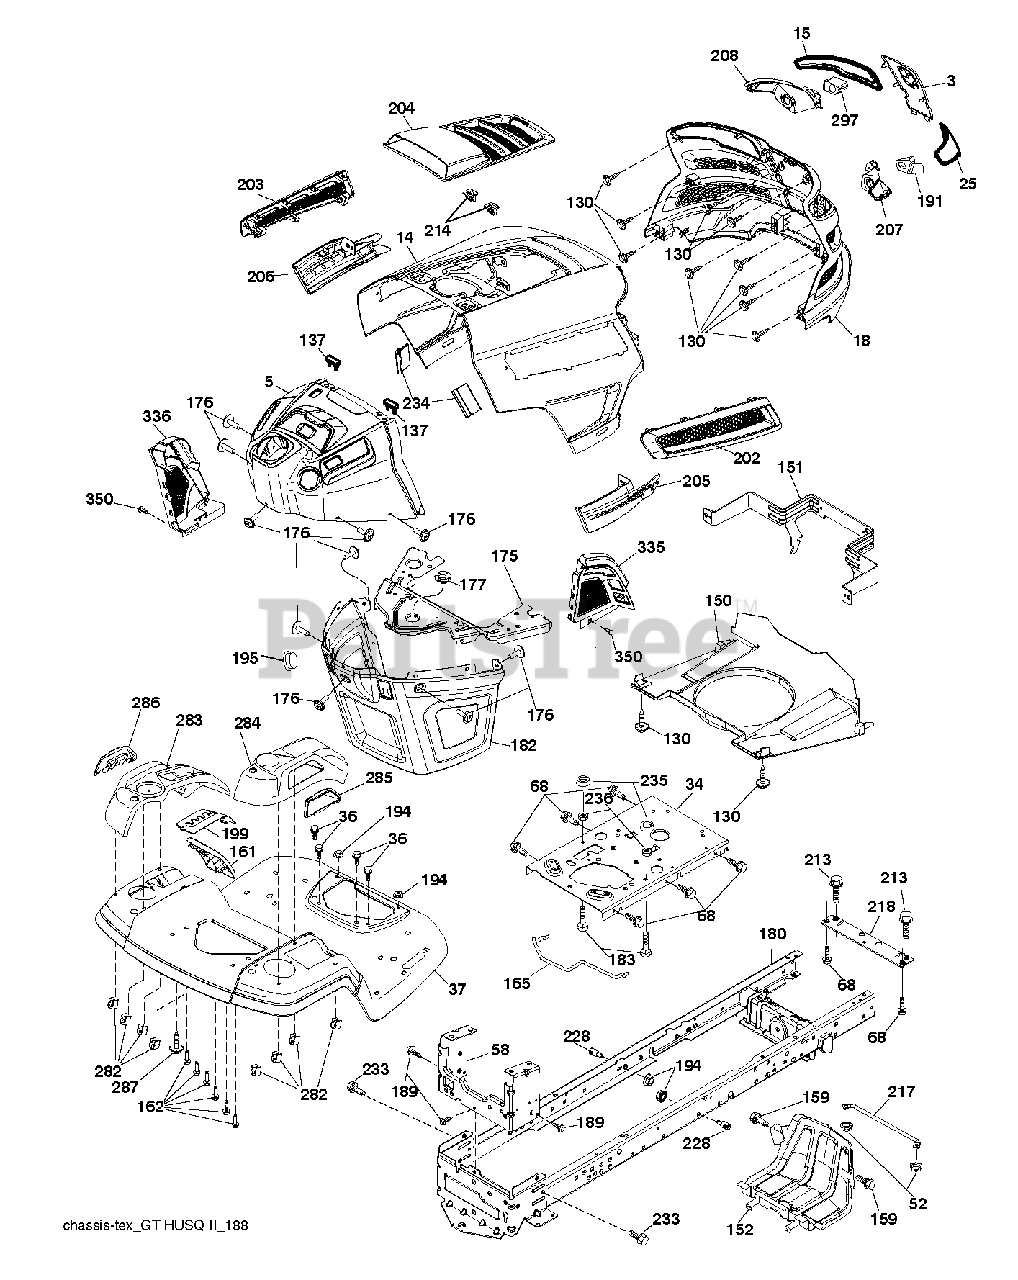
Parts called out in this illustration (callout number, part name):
3	APPLIQUE.SUBASM.GT.HUSQ.II
5	UPPER.ASSY.GT2.498.GRY
14	HOOD.ASM.HUSQVARNA.GT.TEX.ORAN
15	LENS.HEADLIGHT.LH.GTII.2011
18	GRILLE.SUBSTRATE.2011.
25	LENS.HEADLIGHT.RH.GTII.2011
34	PLATE.ENGINE.WELDED.CHASSIS
36	SCREW 5/16"
37	FENDER.TLT.FS.W/CPH/FW/RSF.668
52	LOCKNUT
58	DRAWBAR UPPER 2PC SMALL FENDER
68	SCREW LT
130	SCREW.#10 X 0.750.BOS
137	BUMPER DASH
150	AIR.DUCT.GTV.BLACK
151	BRACKET PIVOT
152	SHIELD.BROWNING.PNT.GT.V2
159	SCREW, 3/8-16X3/4
161	WINDOW.FUEL.LT.HUSQ.TEX.498
162	SCREW.HI-LO.CONSOLE
165	SUPPORT.TANK.REAR.W/TEX
175	PLATE.CROSSMEMBER.HUSQ
176	SCREW.#10-24X5/8.RN.QU
177	BUSHING STEERING
180	CHASS.WLDMNT.TL.12GA/2P.48/54
182	DASH.LOWER.COMMON.12V.ADAPTOR
183	BOLT.5/16-18X1-1/4 FULL THD
189	SCREW
191	INSERT.REFLECTIVE.RH.HUSQ.GTII
194	NUT LOCK HEX FLANGE 5/16-18
195	PLUG.HOLE.DASH.LOWER.12V.BLK
199	PLATE.DECK.LIFT.HUSQ.LT
202	VENT.SIDE.RH.GT.HUSQ.II.
203	VENT.SIDE.LH.GT.HUSQ.II.498
204	VENT.TOP.HUSQ.GT2
205	SIDE.TRIM.RH.GT.HUSQ.II
206	SIDE.TRIM.LH.GT.HUSQ.II.GRAY
207	BEZEL LIGHT.RH.GT.II.MYLAR
208	BEZEL LIGHT.LH.GT.II.MYLAR
213	BOLT
214	CLIP.RETAINER.TINNER.
217	ROD.PIVOT.HOOD
218	X-PIECE.HOOD.STOP.NON/
228	STUD.FASTNER.W/ANTI-ROTATE
233	BOLT.SHOULDER
234	BUMPER.HOOD.TEX.HUSQVARNA
235	SPACER FENDER
236	NUT.CENTERLOCK.5/16-
282	CLIP.RETAINER.CONSOLE.LT.HUSQ
283	CONSOLE.DECK.LIFT.R.SDFL.HUSQ
284	CONCOLE.CNTRL.PDL.HUSQ.LT.498
285	CONSOLE INSERT RH
286	CONSOLE.INSRT.LH.HUSQ.LT.BLACK
287	SCREW 1/4X20
297	INSERT.REFLECTIVE.LH.HUSQ.GTII
335	COVER.LOWER.DASH.RH.BLACK
336	COVER-LH.LOWER.DASH.GT2.BLACK
350	CLIP.X-MAS.TREE
